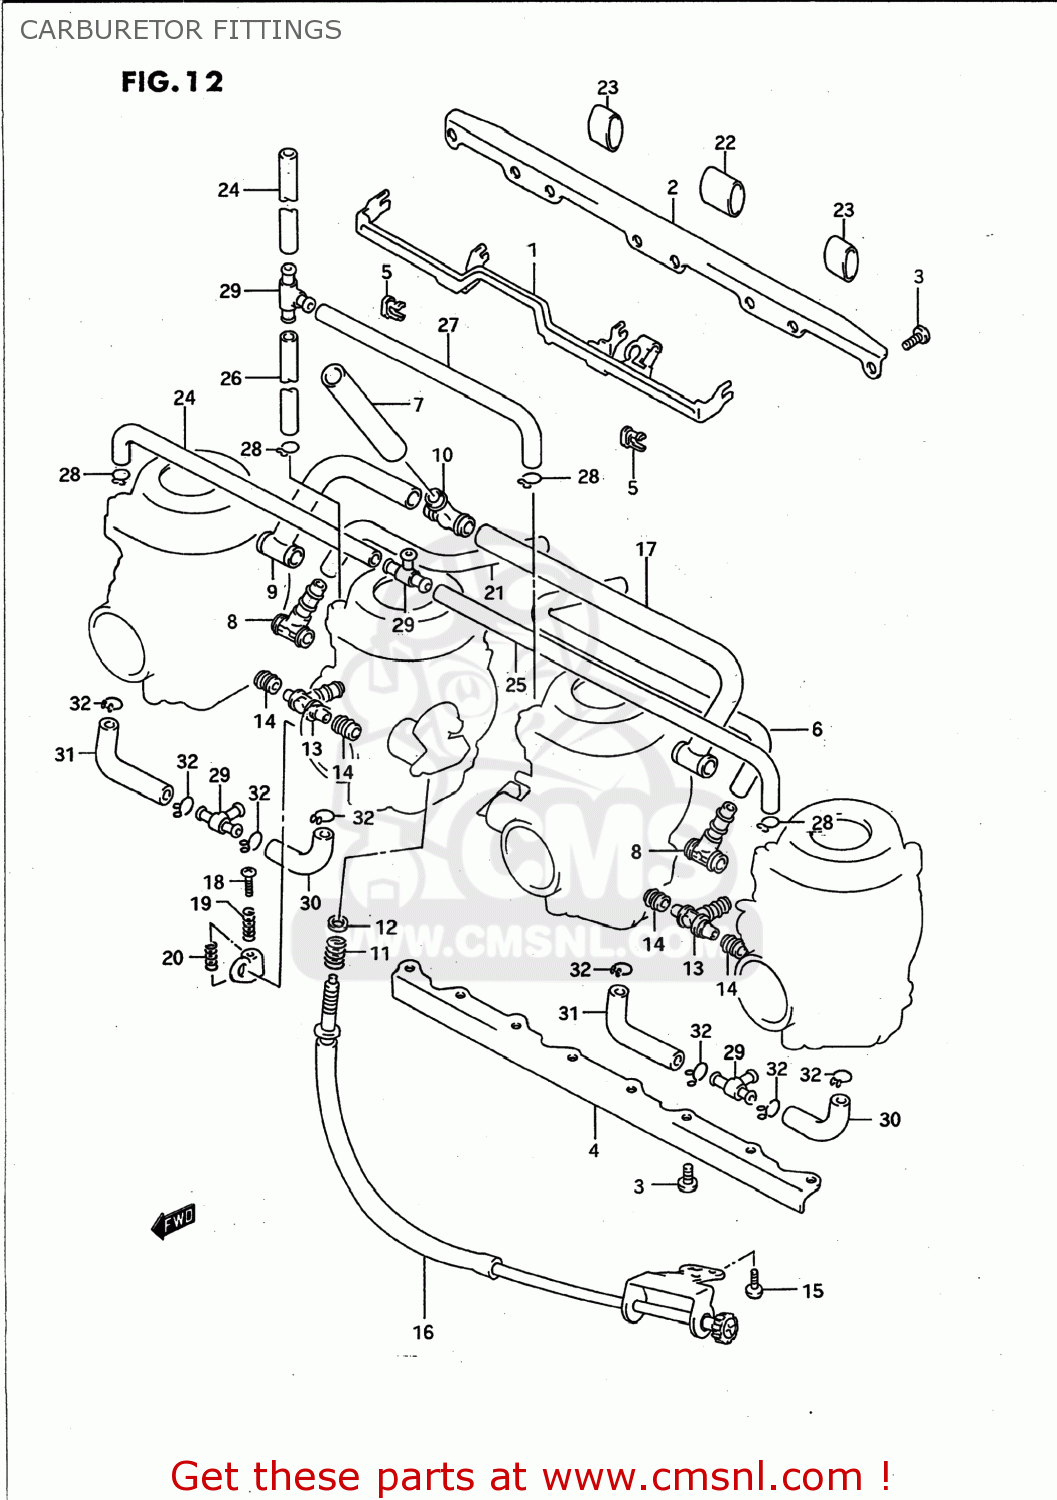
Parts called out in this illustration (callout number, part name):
1	LEVER,STARTER
2	PLATE
3	SCREW
4	PLATE
5	HOLDER
6	HOSE
7	HOSE
8	HOSE
9	HOSE
10	NIPPLE
11	SPRING
12	WASHER
13	NIPPLE
14	SEAL
15	SCREW
16	ADJUSTER ASSY
17	HOSE ASSEMBLY
18	SCREW
19	SPRING
20	SPRING
21	HOSE
22	HOSE
23	HOSE
24	HOSE
25	HOSE
26	HOSE
27	HOSE
28	CLIP
29	NIPPLE
30	HOSE
31	HOSE
32	CLIP
